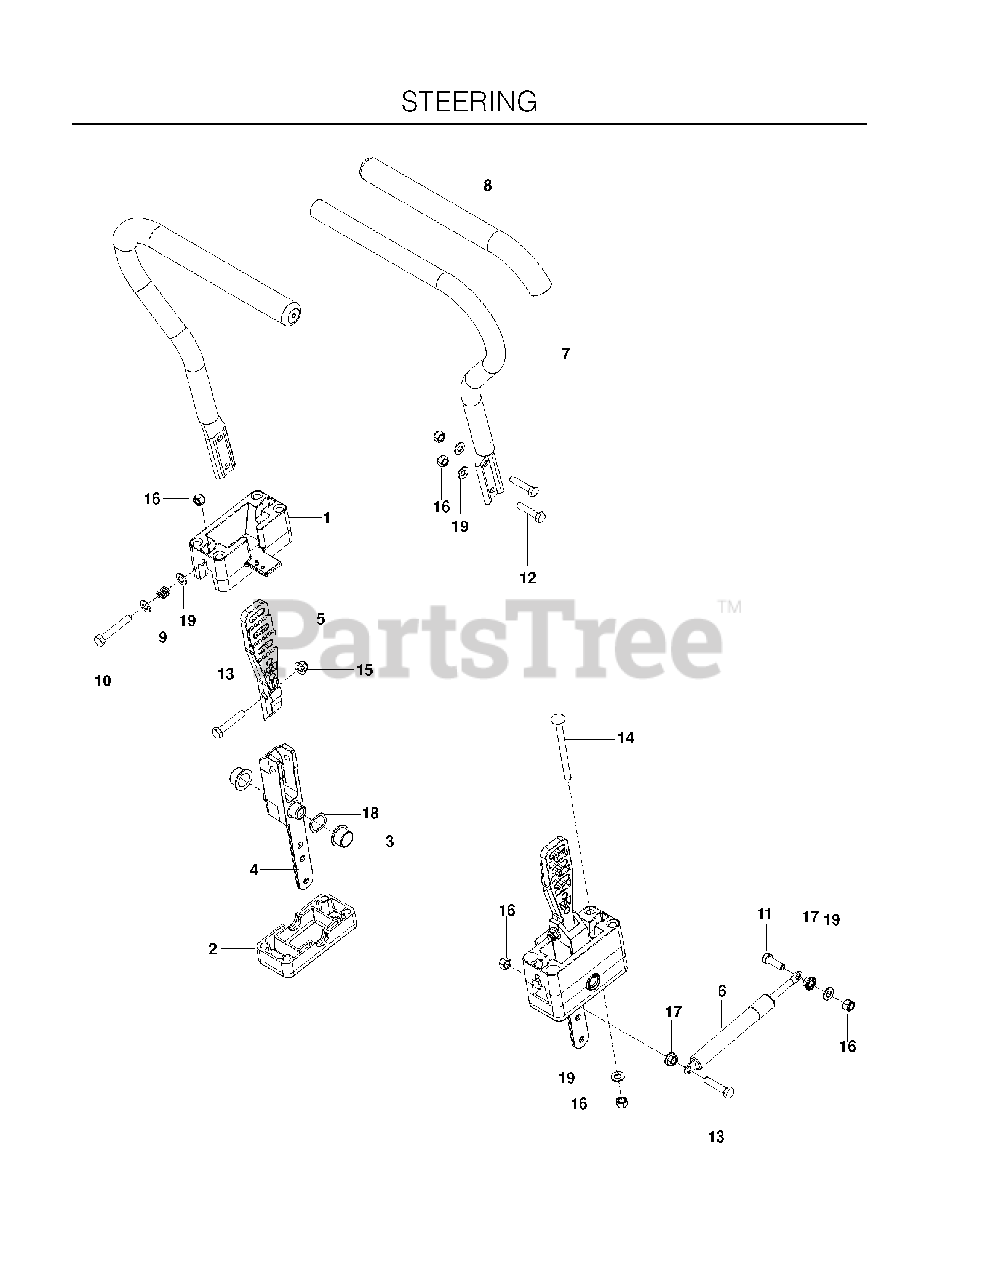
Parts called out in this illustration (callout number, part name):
1	BLOCK, UPPER
2	BLOCK, LOWER
3	BEARING, FLANGE
4	PIVOT SECTION, DRIVE CONTROL
6	DAMPENER
7	ASSEMBLY, DRIVE LEVER
8	GRIP, FOAM (GROUND) 15
10	HCS 5/16-18 X 2 TPBLT GR 5 ZD
11	HCS 5/16C X 1
12	CAPSCREW 5/16 X 1/1/2 HEX HEAD
13	HCS 5/16C X 1 3/4
14	RHSNB 5/16-18 X 4 GR 5 ZD
15	5/16-18 NYLOC FLANGE NUT
16	NUT 5/16 NYLOC
17	NUT 5/16C WHIZ
18	WASHER, .825 X 1.087, WAVE
19	FLAT WASHER 5/16 SAE
